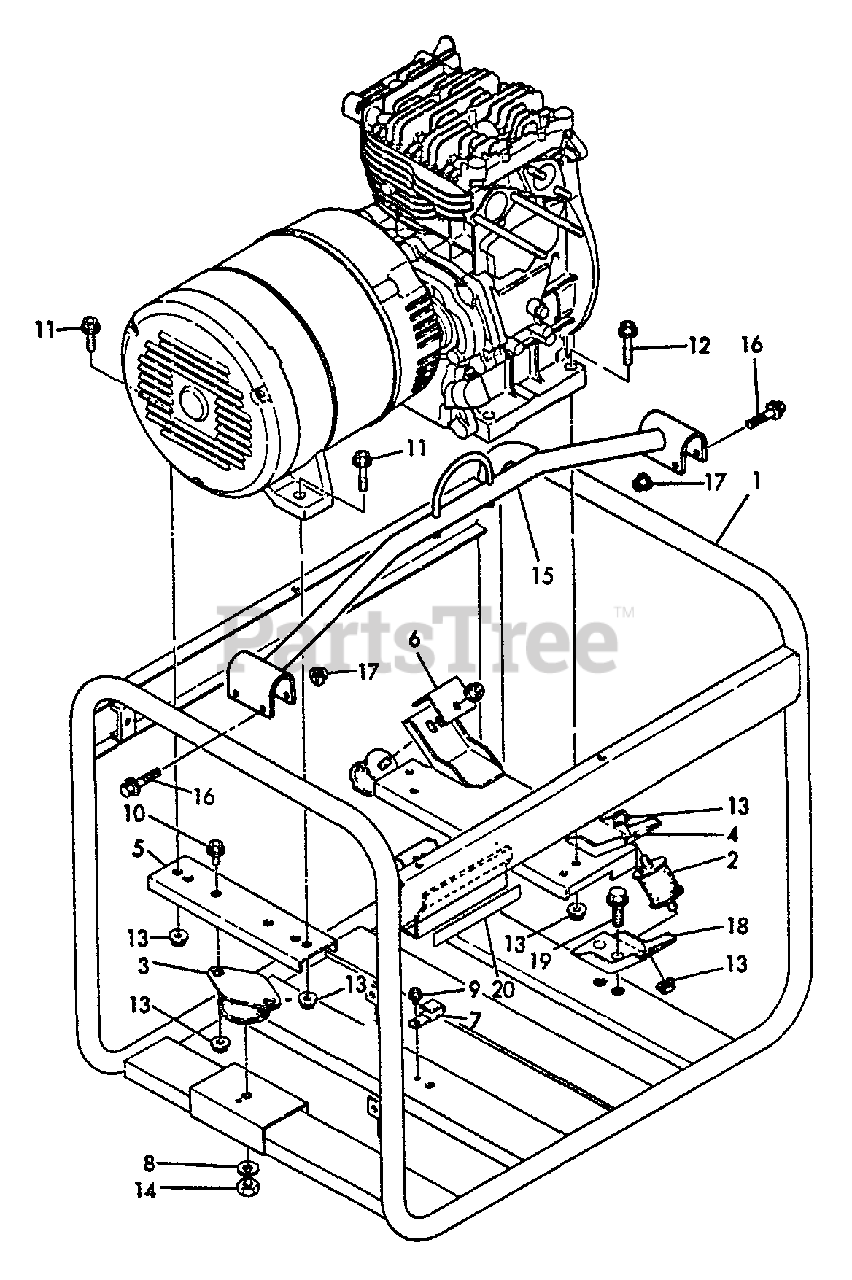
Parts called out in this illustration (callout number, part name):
1	FRAME
2	DAMPER, FRONT
3	DAMPER, REAR
4	STAY, DAMPER
5	STAY, REAR DAMPER
6	COVER, DAMPER
7	CLAMP
8	LOCKWASHER - 10
9	BOLT - 6X8 -- PLATED
10	BOLT - 8X20 -- PLATED
11	BOLT - 8X30 -- PLATED
12	BOLT - 8X38 -- PLATED
13	NUT - 8
14	NUT - 10
16	BOLT - 6X40
17	NUT - 6 -- FLANGE
18	DAMPER STAY, LOWER
19	BOLT - 8X16 -- PLATED
20	SHEET, FRAME
